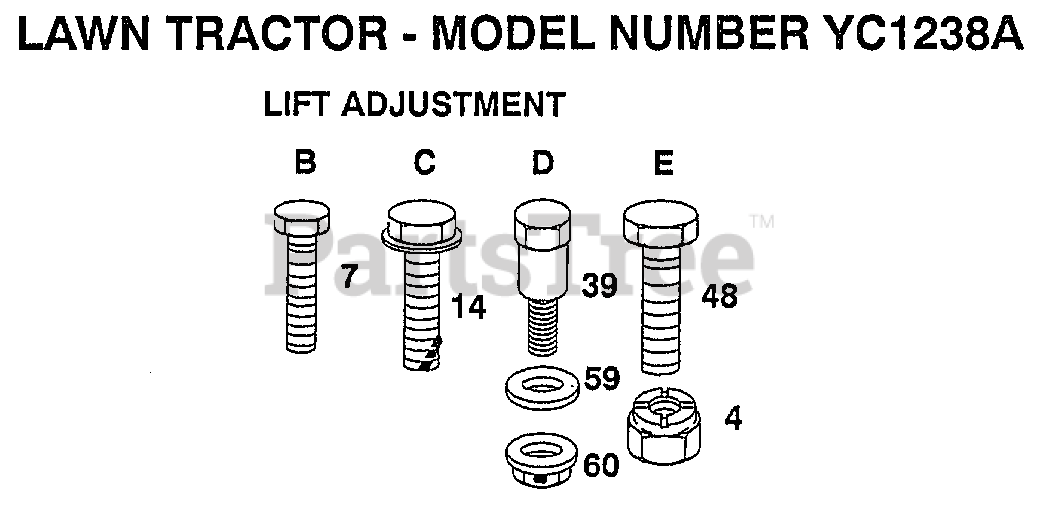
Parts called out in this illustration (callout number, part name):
7	SCREW
14	SCREW HEX CRT
39	"BOLT, SHOULDER LT"
59	WASHER T
60	NUT SPECIAL T
